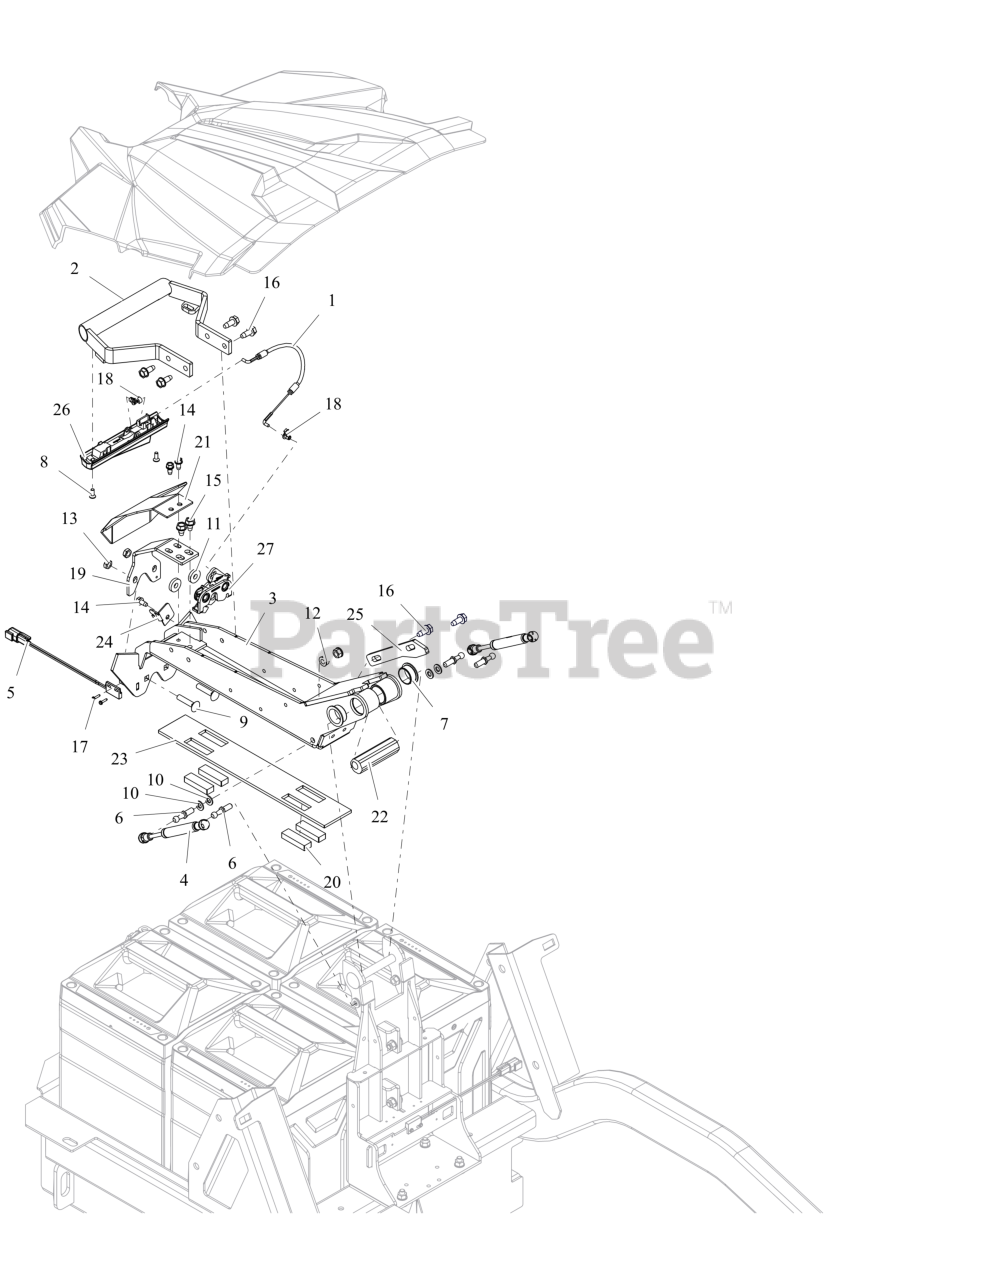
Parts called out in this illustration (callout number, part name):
1	CABLE, HOOD RELEASE
2	WLDMT, HANDLE (RED)
3	WLDMT, MAIN HOLD DOWN (RED)
4	DAMPER, GAS
5	SWITCH, MAGNETIC
6	STUD-BALL-THREADED
7	BSHG-FLG 1.0X1.125X.50X1.375 R
8	SCR, FLCSKH M5-0.8X14 GR10.9 ROHS
9	BLT,RHSN .31-18X1.50 G5 ZCC
10	WSHR,FLT .323X.625X.062 ZCC
11	WSHR, FLT .328X.870X.179 ZCC
12	NUT,LK-CTR-FLG .31-18 GF ZCC
13	NUT-LK-CTR-JAM .312-18 GB ZCC
14	SCR-TAP .25-20X.50 HWH ZCC
15	SCR,TAP .312-18X.50 HWH TR ZCC
16	SCR,TAP .312-18X.75 HWH TR ZCC
17	SCR-TAP #4-40X.50 HWH ZCC
18	CLIP, RETAINER
19	BRKT, LATCH MTG (RED)
20	PAD, RUBBER
21	COVER, LATCH (RED)
22	ECCENTRIC, HOOD LATCH-FRONT
23	PAD, RUBBER
24	RETAINER, CABLE (BLACK)
25	STOP, HOOD (BLACK)
26	HANDLE, SQUEEZE ACTUATOR
27	LATCH, PUSH TO CLOSE
